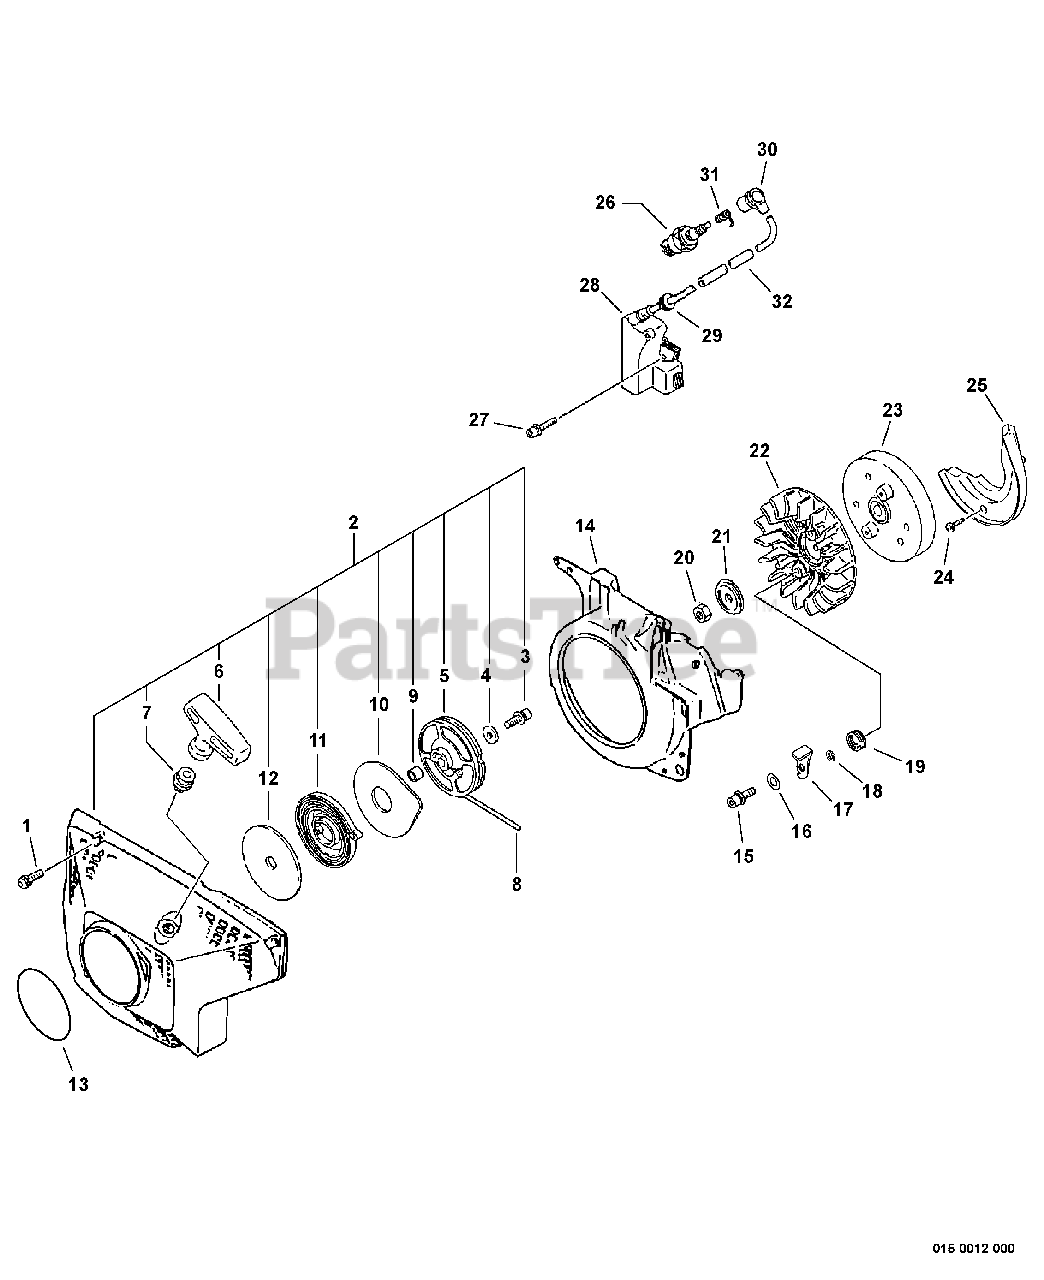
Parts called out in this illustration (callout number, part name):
1	SCREW - 5X20
2	STARTER ASSY
3	SCREW - 5X14
4	WASHER - 5
5	REEL, ROPE
6	GRIP, STARTER
7	GUIDE, ROPE
8	ROPE, STARTER - 4X950
10	PLATE, STARTER
11	SPRING, REWIND
12	PLATE, STARTER
13	LABEL - ECHO
14	SHIELD, FAN
15	SCREW - 5X30
16	WASHER - 5
17	PAWL, STARTER
19	SPRING, RETURN
20	NUT - FLANGE
21	WASHER - CUP
23	FLYWHEEL
24	SCREW - 5X20
25	SHIELD, FAN
26	SPARK PLUG -- BPM-7A
27	SCREW - 4X20
28	COIL, IGNITION
30	CAP, SPARK PLUG
31	TERMINAL, SPARK PLUG CAP
